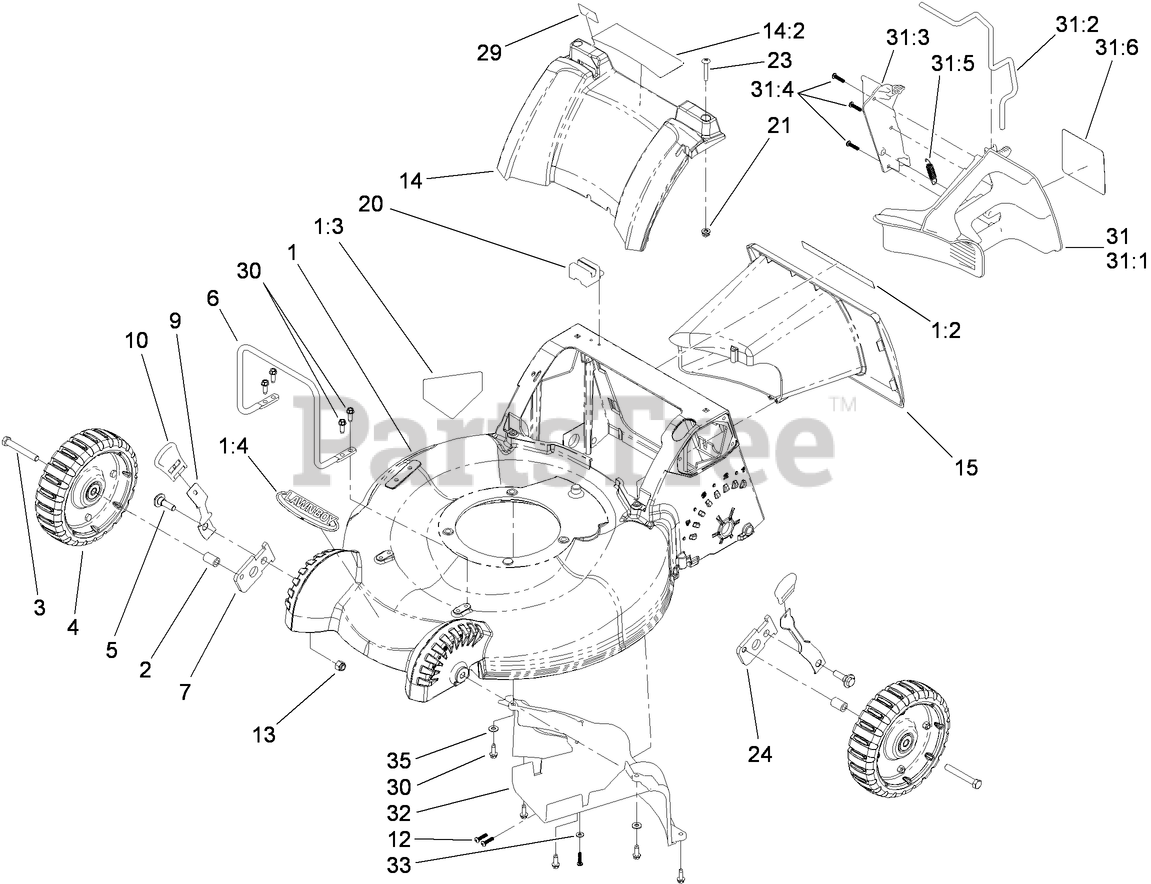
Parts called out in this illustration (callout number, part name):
1	HOUSING
1:2	DECAL-SAFETY
1:3	DECAL-DANGER
2	SPACER
3	SCREW-HH
4	8 INCH WHEEL ASM
5	SCREW-SHOULDER, HWH
6	GUARD-ENGINE
7	ARM-PIVOT, RH
9	ARM-SPRING, FRONT
10	KNOB-HOC
12	SCREW-PLASTITE
13	NUT-LOCK, NI
14	COVER-REAR
14:2	DECAL-SAFETY
15	TUNNEL
20	MODULE-SWITCH
21	NUT-CLIP
23	SCREW-PTH
24	ARM-PIVOT, LH
29	DECAL-BAG ATTACHMENT
30	SCREW-HWHTF
31	MULCH PLUG ASM
31:1	PLUG-MULCH, LH
31:2	LATCH-PLUG, MULCH
31:3	PLUG-MULCH, RH
31:4	SCREW-PLASTITE
31:5	SPRING-EXTENSION
31:6	DECAL-PLUG, MULCH
32	BAFFLE-REAR
33	WASHER-FLAT
35	WASHER-FLAT
